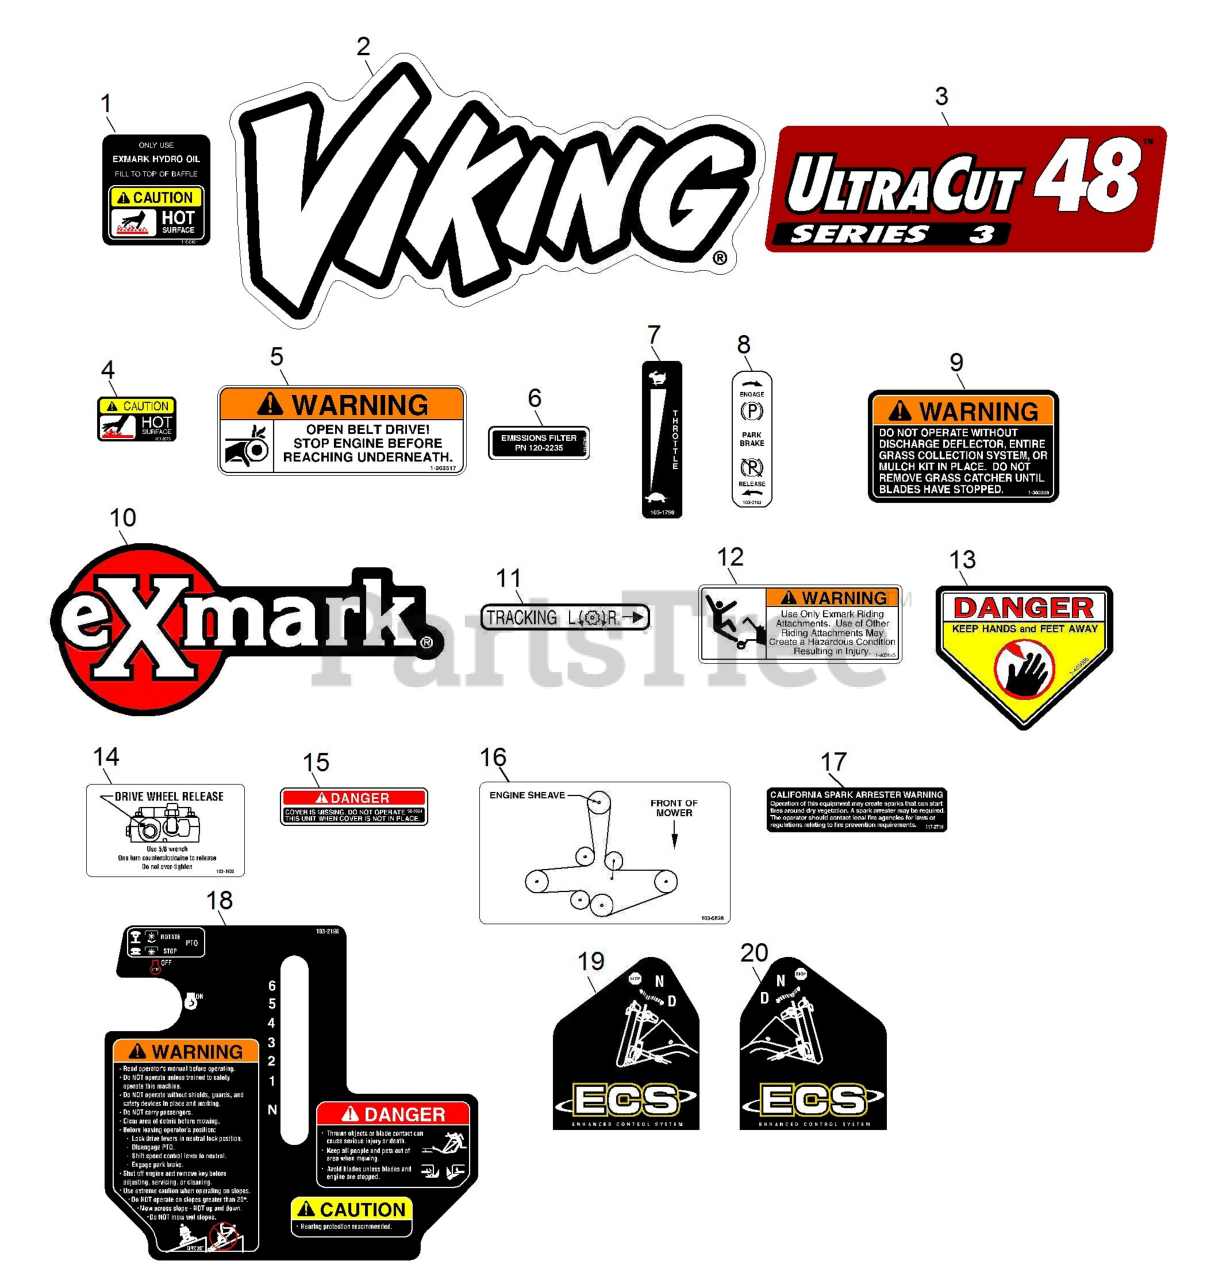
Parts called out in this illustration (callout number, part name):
1	DECAL-HYDRAULIC TANK
2	DECAL,VH MODEL
3	DECAL-ULTRACUT 48 SERIES
4	DECAL-CAUTION
5	DECAL,BELT DRIVE
6	DECAL-FILTER, EMISSIONS
7	DECAL,THROTTLE ONLY
8	DECAL-BRAKE, PARK
9	DECAL-WARNING, DISCHARGE
10	DECAL,EXMARK LOGO
11	DECAL,TRACKING ADJUST
12	DECAL,SULKY WARNING
13	DECAL-DANGER
14	DECAL,DRIVE RELEASE
15	DECAL-COVER, MISSING
16	DECAL,BELT ROUTING
17	DECAL-ARRESTER, SPARK
18	DECAL,CONSOLE VH ECS
19	DECAL,LH ECS INSTRUCTION
20	DECAL,RH ECS INSTRUCTION
